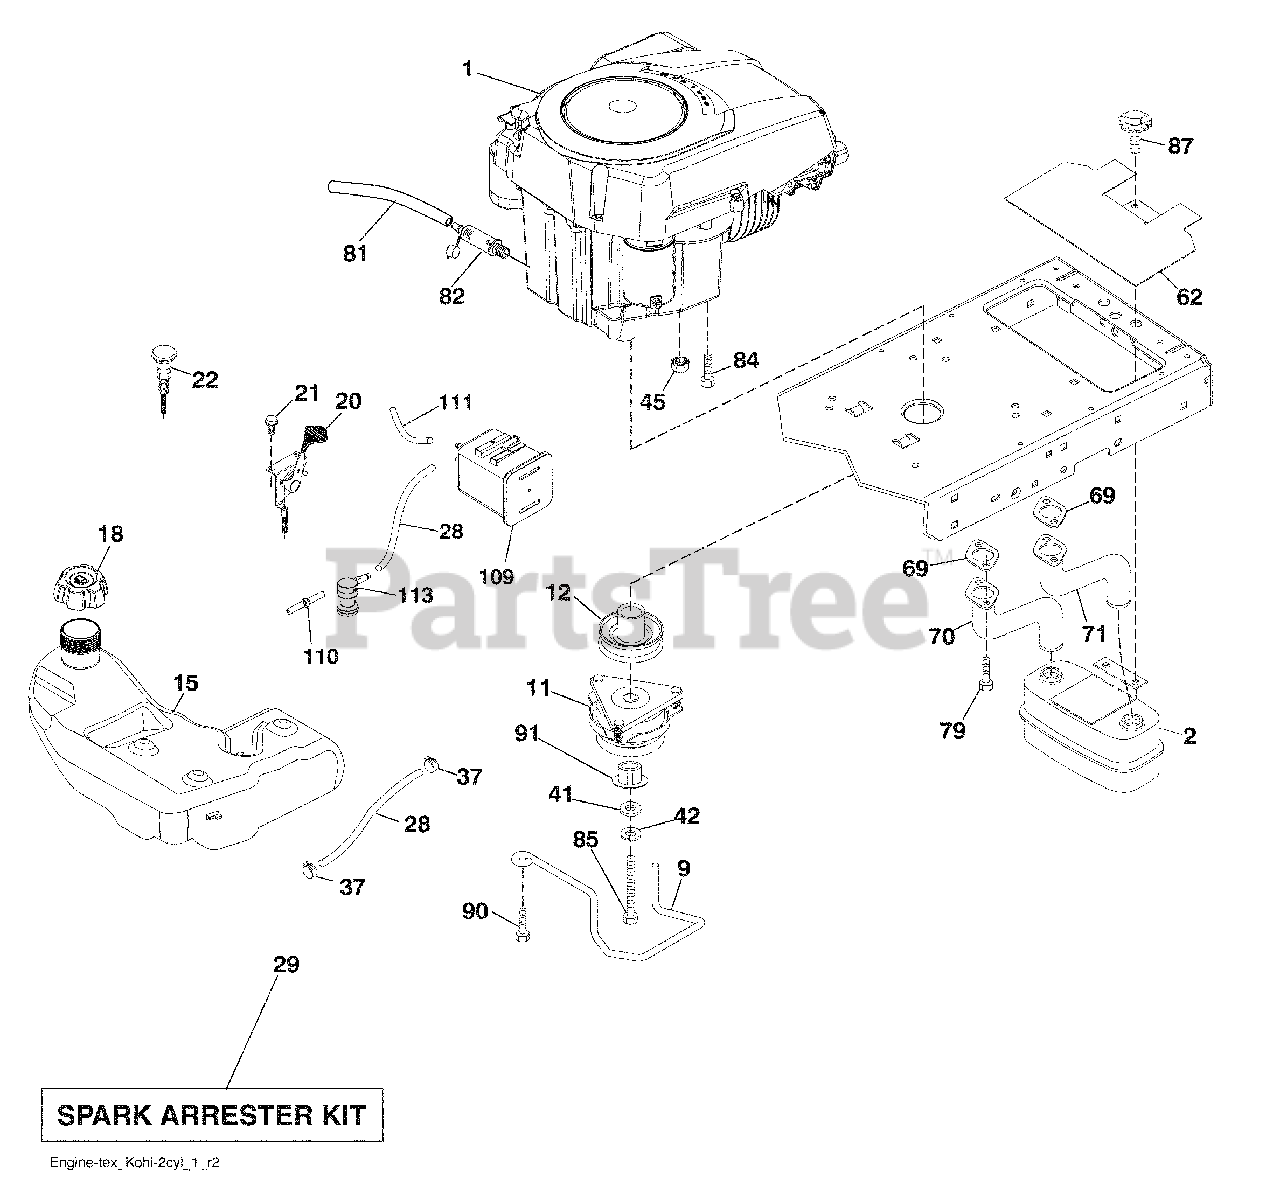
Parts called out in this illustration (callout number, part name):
9	Keeper Belt Engine
11	Clutch Electric
12	Pulley Engine
15	Tank Fuel 4.0
18	Cap Asm
20	Control Throttle
21	Screw #10 x 0.750 BOS Thread
22	Control Choke
28	Fuel Line
29	Spark Arrester Kit
37	Clamp Hose
41	Washer 1-1/2 OD x 15/32 ID x .250
42	Washer Lock 7/16
45	Nut Keps Hex 1/4-20 unc
62	Shield Heat Muffler
69	Gasket
70	Tube Exhaust LH
71	Tube Exhaust RH
79	Screw Socket Head 5/16-18 x .75
81	Tube Drain Oil Easy
82	Plug Drain Oil
84	Screw 3/8-16 x 1
85	Bolt Hex 7/16-20 x 3.75 Gr. 5
87	Bolt 5/16-18 unc x 1 w/Sems
90	Screw 3/8-16 x 1
109	Canister Carbon Filter Asm.
110	Valve Anti-Slosh
111	Purge Line
113	Valve Slant Cartrdg.
